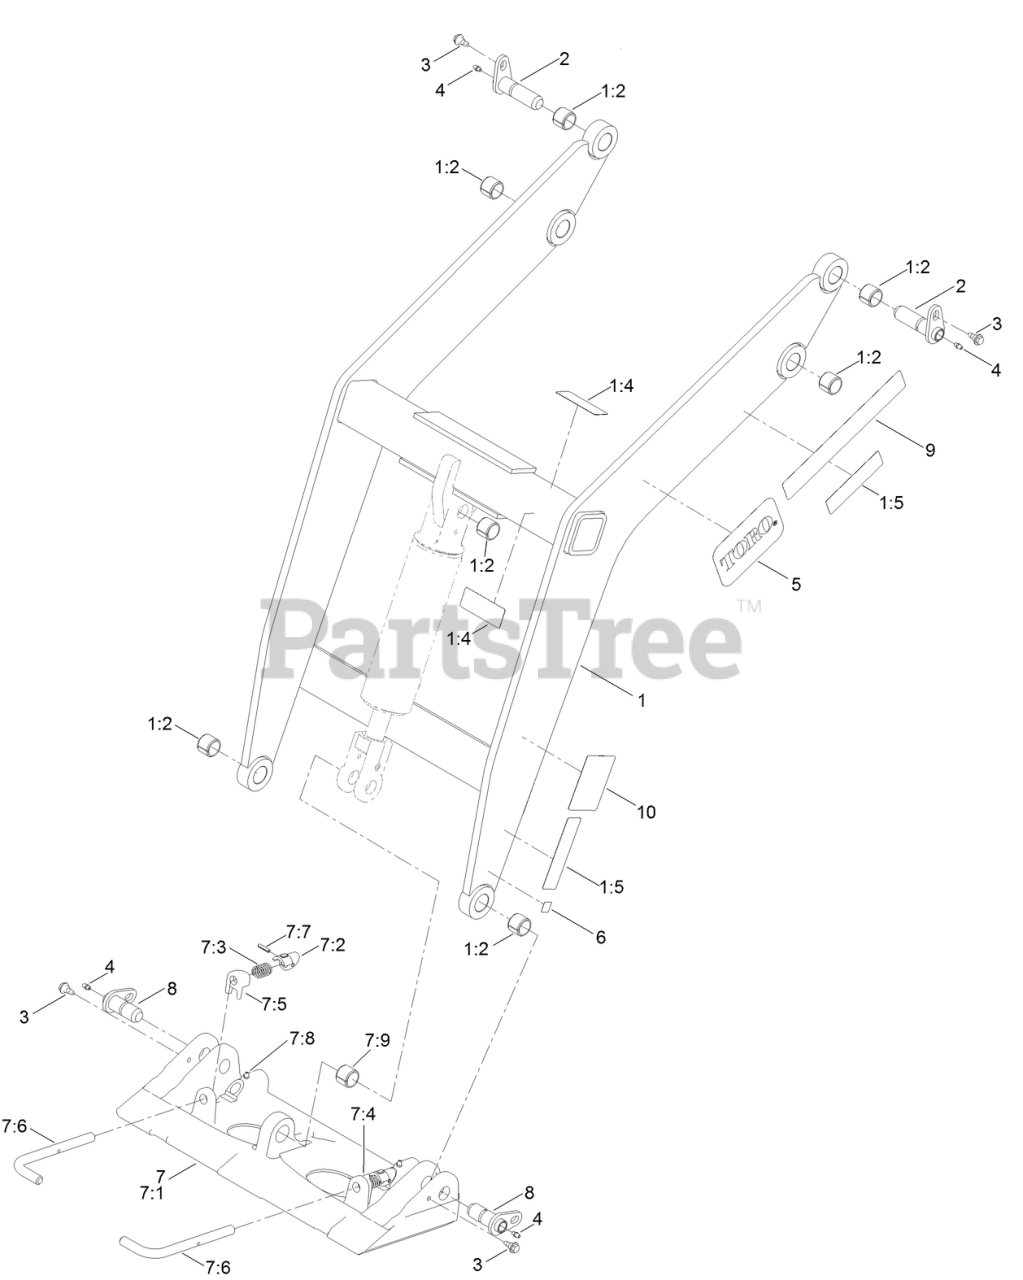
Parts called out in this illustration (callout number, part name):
1	LOADER ASM
1:2	BUSHING-TENSION
1:4	DECAL-WARNING, NO RIDER
1:5	DECAL-WARNING, CRUSHING
2	PIN-PIVOT
3	BOLT-SHOULDER
4	FITTING-GREASE
5	DECAL
6	DECAL-POINT, LIFT
7	QUICK ATTACH ASM
7:1	MOUNT-QTACH
7:3	SPRING-COMPRESSION
7:4	STOP-RH
7:5	STOP-LH
7:6	PIN-LOCKING
7:7	PIN-GROOVED
7:8	FITTING-GREASE
7:9	BUSHING-TENSION
8	PIN-PIVOT
9	DECAL- E-DINGO
10	DECAL-WARNING, BUCKET
